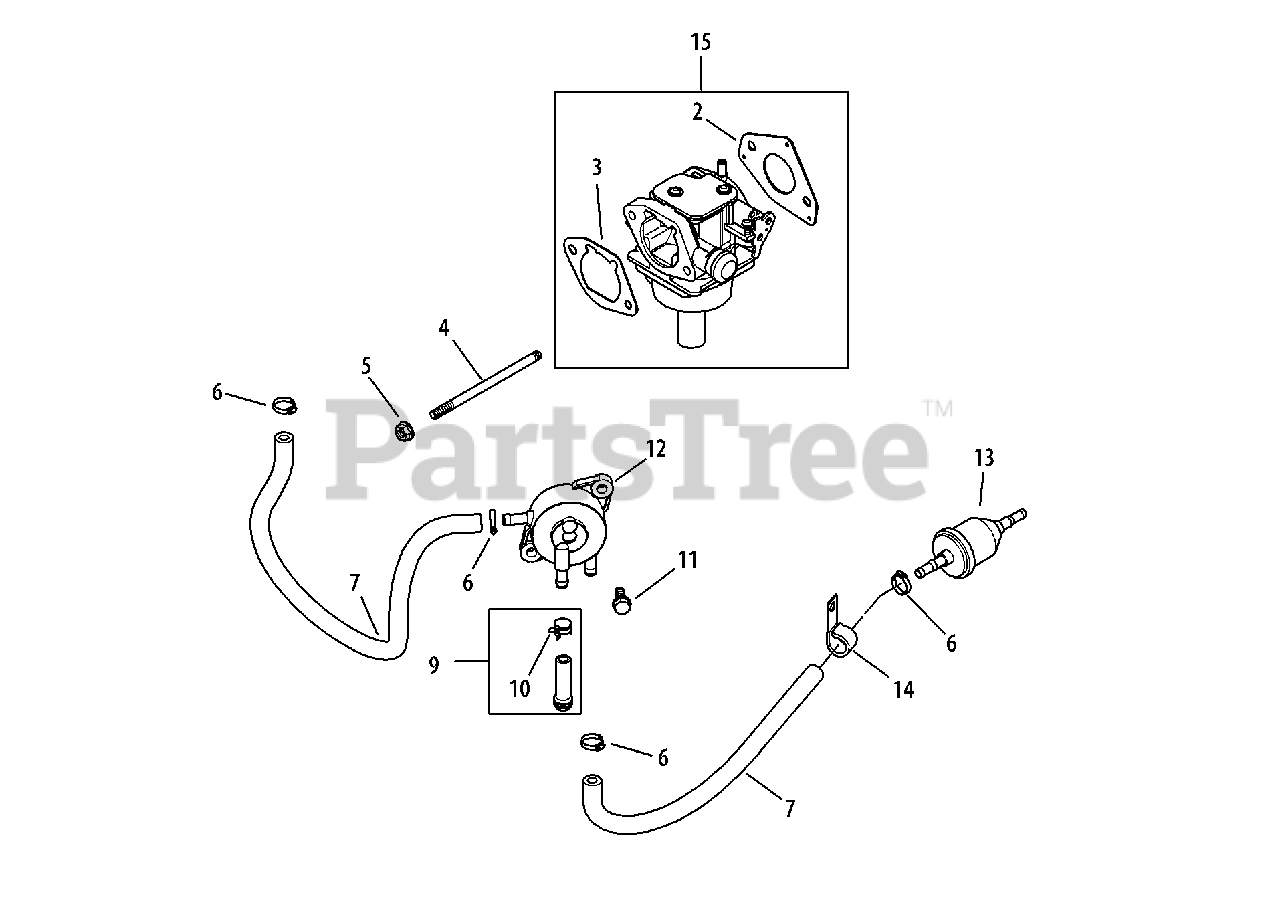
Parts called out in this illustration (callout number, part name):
2	Carburetor Gasket
3	Air Cleaner Base Gasket
4	Stud, M6 X 1.0 X 106
5	Flg. Nut, M6 X 1.0
6	Hose Clamp, 1/2
11	Tap Screw, M6 X 1.7 X 18
15	Carburetor Kit, 19mm (Inc. 2 & 3)
